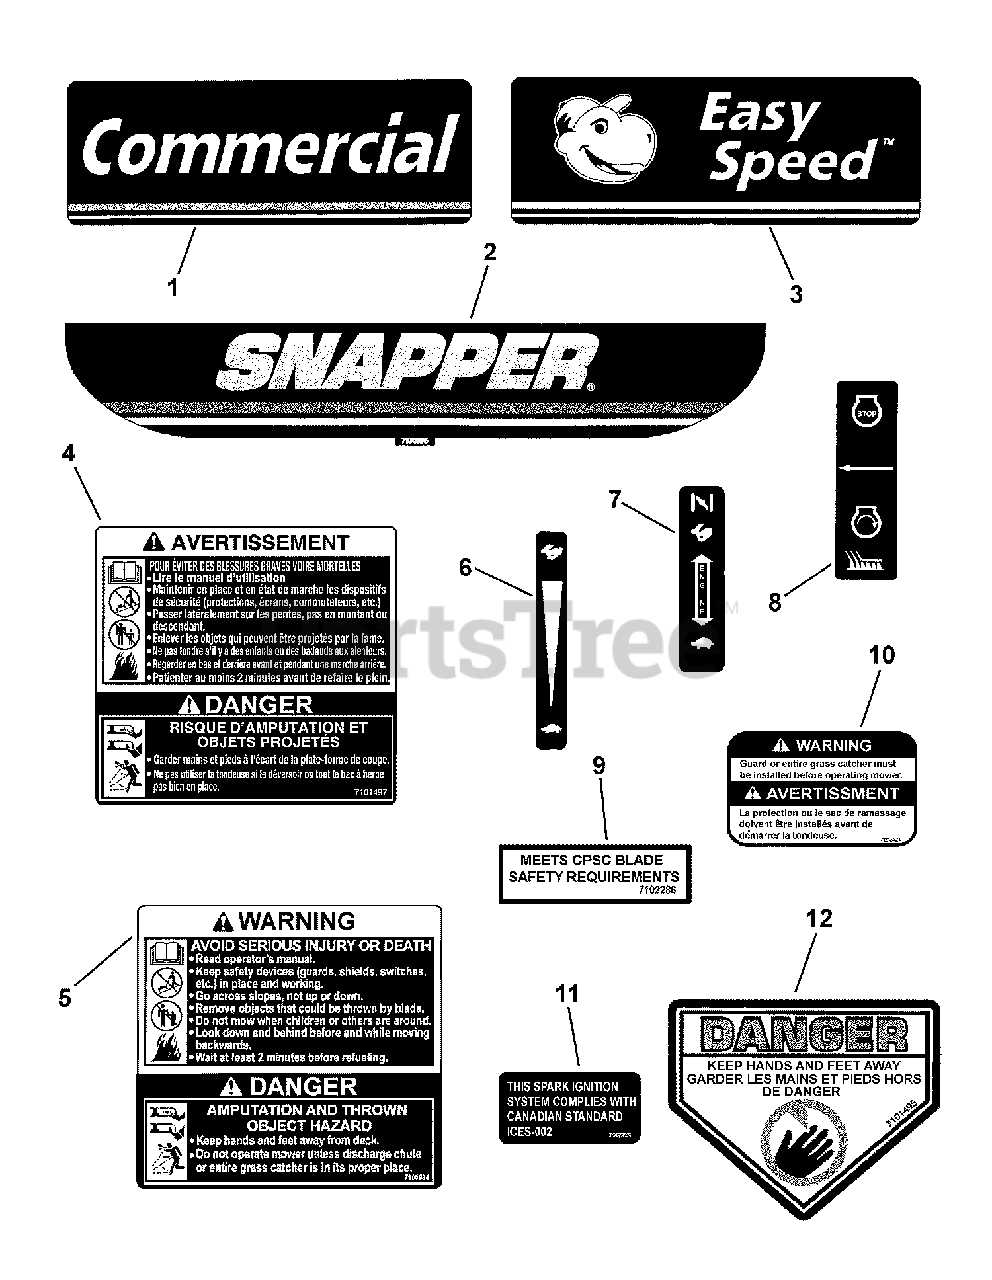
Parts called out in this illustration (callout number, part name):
1	DECAL, Commercial, Control Panel
2	DECAL, SNAPPER, Steel Decks
3	DECAL, Easy Speed, Control
4	DECAL, Warning/Danger/French/English
5	DECAL, Warning/Danger WBM
6	DECAL, Speed Shift
7	DECAL, Throttle Control, KWV
8	DECAL, OPC Bail (International Symbol)
9	DECAL, CPSC Blade
10	DECAL, Chute/Deflector FC
11	DECAL, Compliance, ICES
12	DECAL, CPSC, French/English
